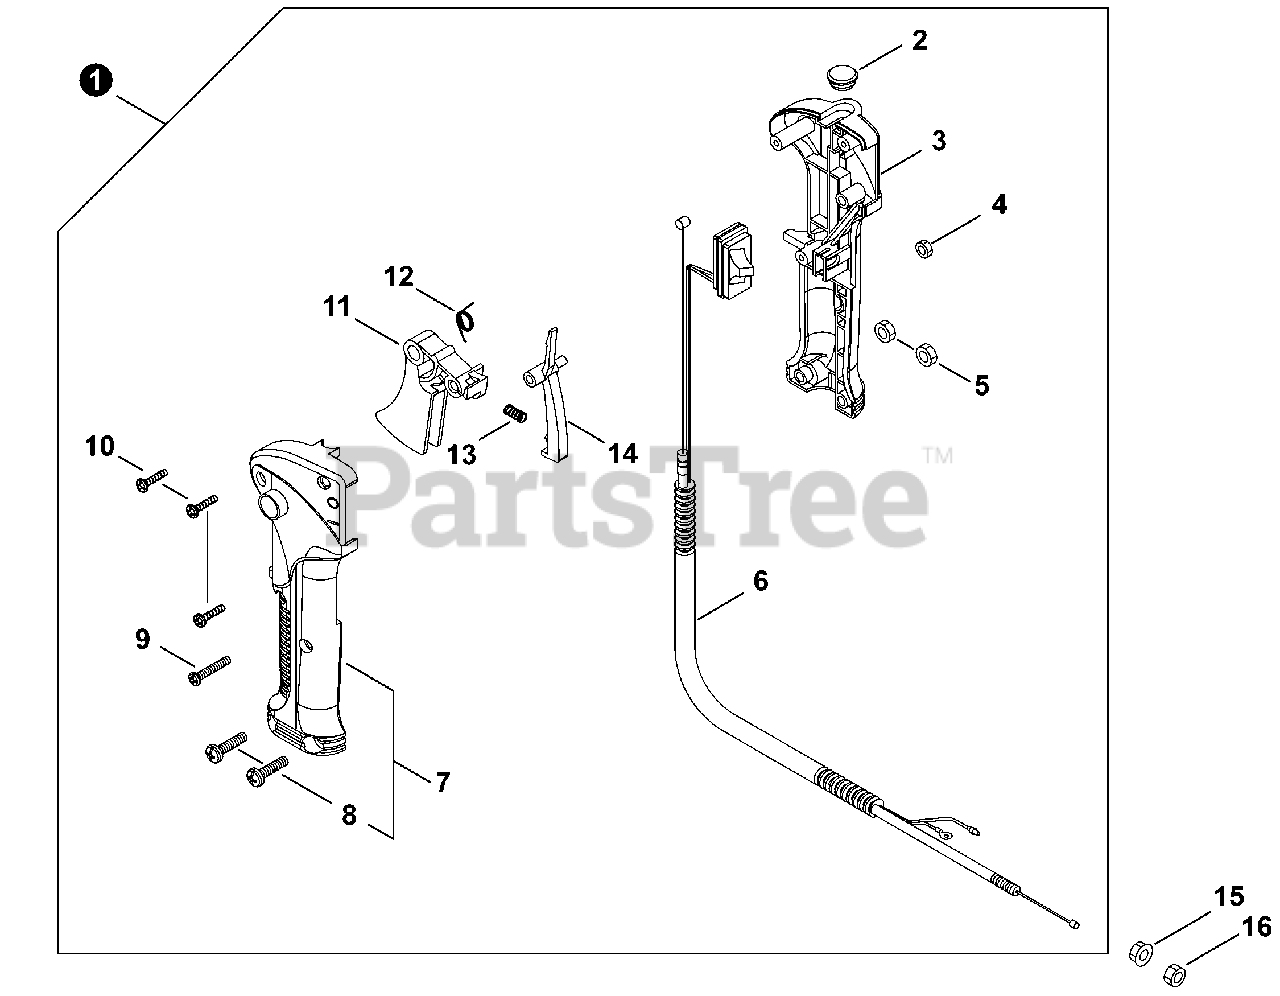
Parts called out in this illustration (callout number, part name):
1	THROTTLE CONTROL ASSY
2	PLUG, RUBBER
3	CONTROL HANDLE - RIGHT
6	CABLE ASSY, CONTROL
7	CONTROL HANDLE KIT
8	SCREW M5×22
9	SCREW M4×23
10	SCREW, TAPPING 4×16
11	TRIGGER, THROTTLE
12	SPRING, TORSION
13	SPRING, COMPRESSION
14	LOCKOUT, THROTTLE
15	NUT, FLANGE M6
